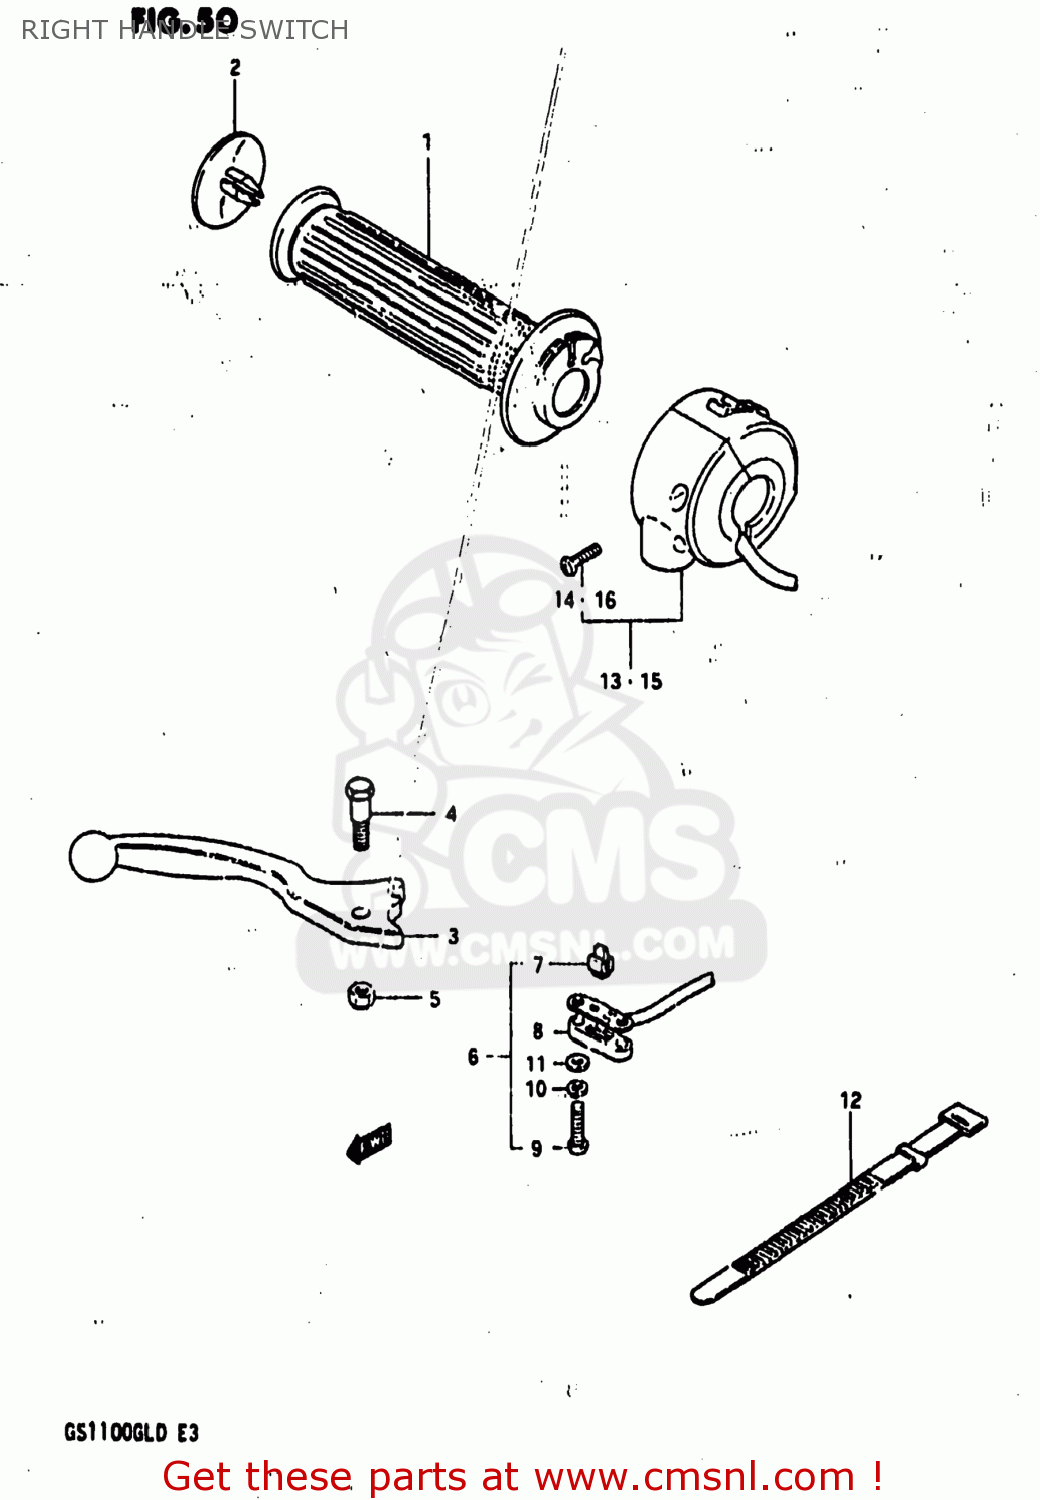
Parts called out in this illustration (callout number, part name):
1	GRIP,THROTTLE
2	CAP,GRIP END
3	LEVER,BRAKE
4	BOLT
5	NUT 6MM
6	SWITCH ASSEMBLY
7	CONTACT,SWITCH
8	COVER,FR BK TERMINAL BASE
9	SCREW
10	LOCK WASHER
11	WASHER
12	CLAMP(L:120)
13	SWITCH ASSEMBLY,HANDLE,RIGHT
14	SCREW
15	SWITCH ASSEMBLY,HANDLE,RIGHT
16	SCREW
